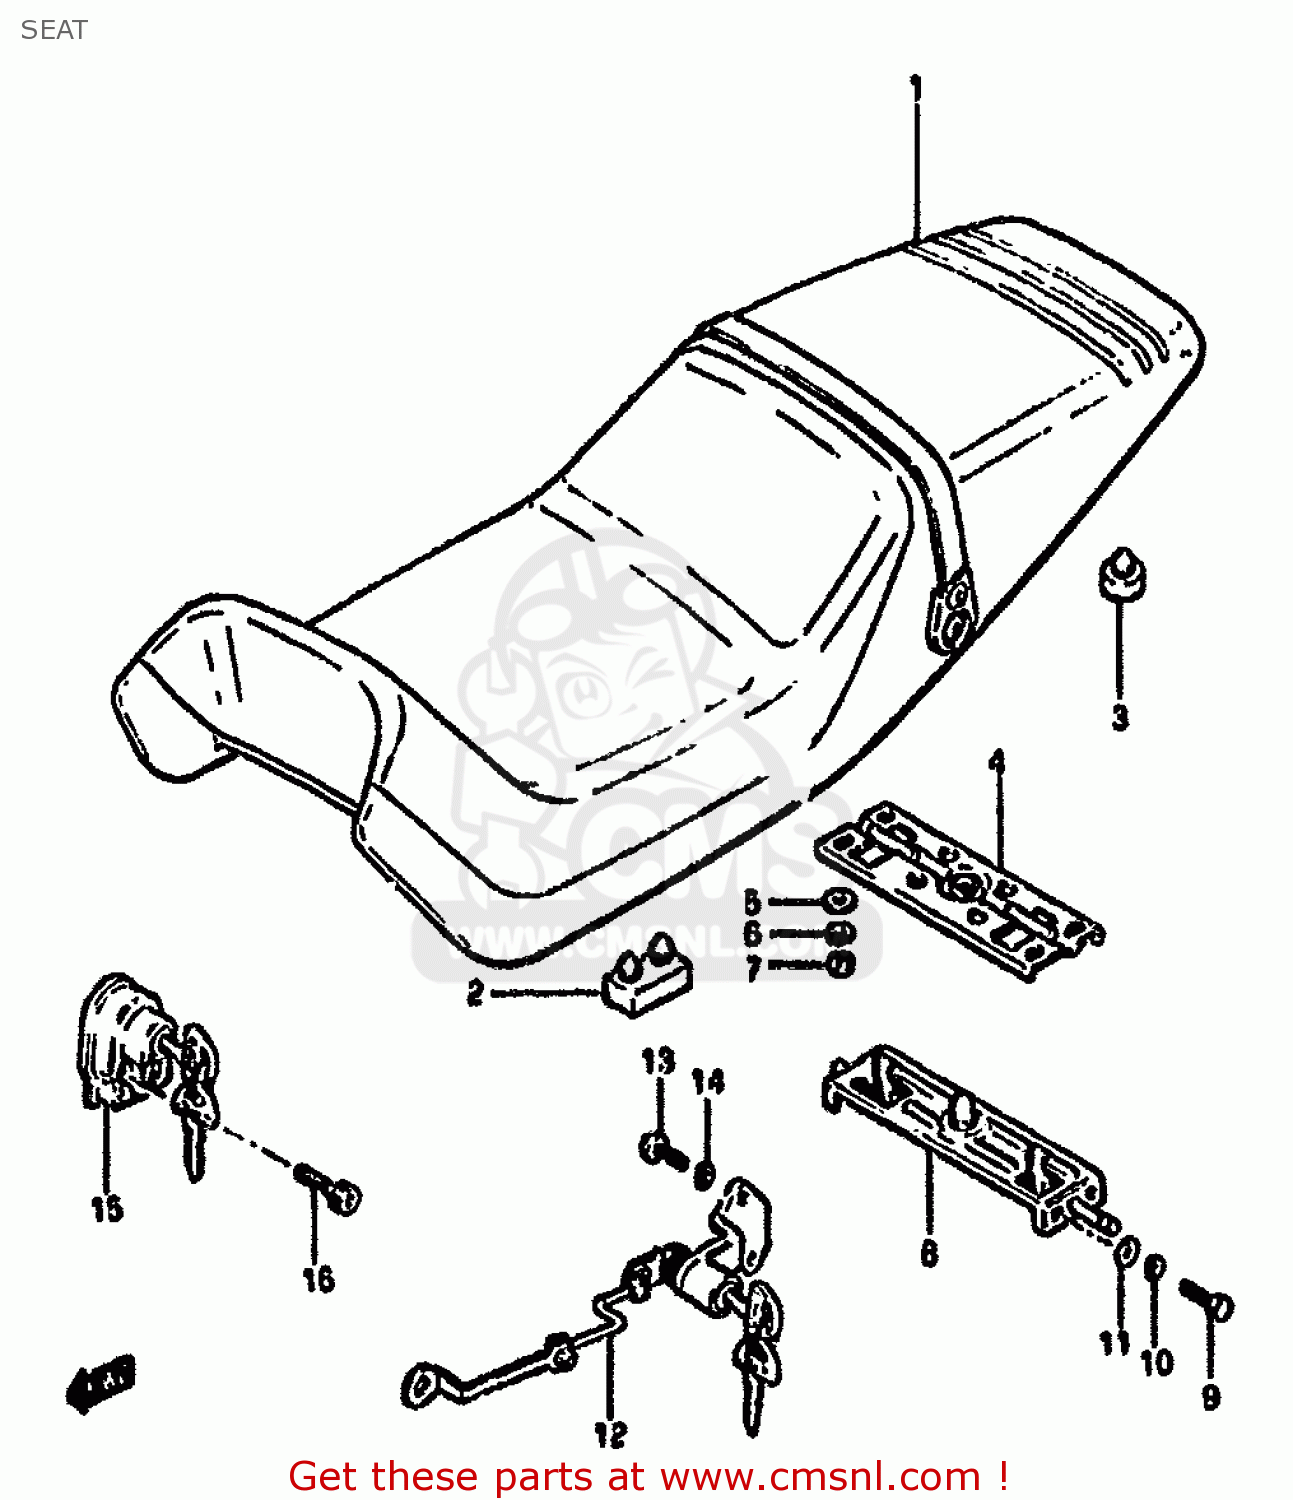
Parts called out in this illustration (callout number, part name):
1	SEAT ASSEMBLY
2	CUSHION
3	CUSHION
4	PLATE,SEAT LOCK GUIDE
5	WASHER
6	LOCK WASHER
7	NUT 6MM
8	CLAMP, SEAT
9	BOLT
10	LOCK WASHER
11	WASHER
12	LOCK ASSEMBLY,SEAT
13	SCREW RH & LH
14	LOCK WASHER
15	LOCK ASSY,HELMET
16	BOLT 5X25
